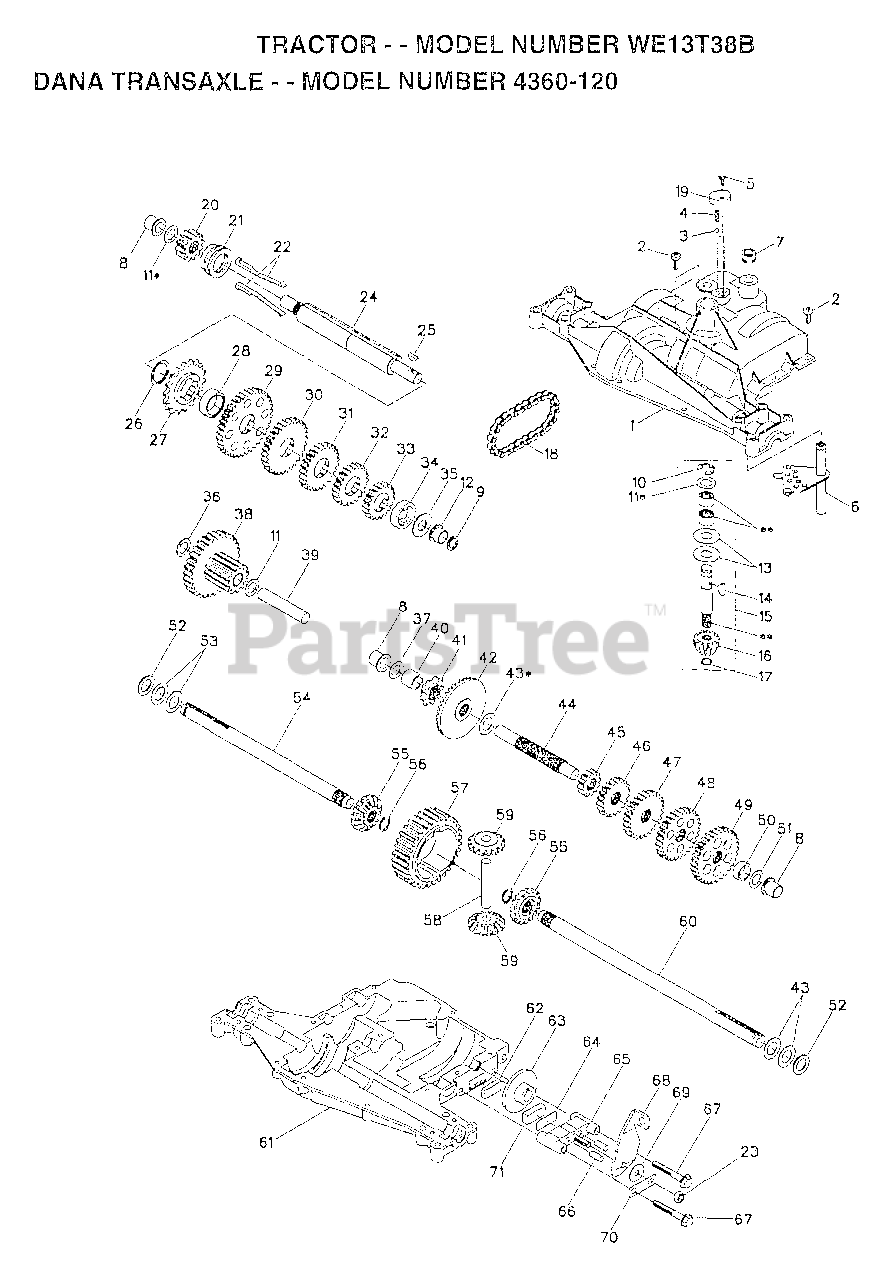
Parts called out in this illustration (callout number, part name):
1	HOUSING.UPPER.DANA.(5305J)
4	"SPRING, DETENT LT"
5	SCREW.TAPPING.1/4-20X.734
6	KIT SHIFTER ASM
9	SEAL.OIL.DAN.5508
10	RETAINING RING LT
11	ASM KIT SHIM 4689
12	BEARING.FLNG.5511
13	WASHER T
14	KEY WOODRUFF-DANA
15	INPUT SHAFT KIT 6250
16	PINION.BEVEL.12T(5620)
17	"RING,RETAINING LT"
18	"CHAIN,24 PTCH LT"
19	COVER.DETENT.(5584)
20	GEAR.SPUR.12T.(5627)
21	CLUTCH.COL.5467
22	ASM KIT CLTCH KEY
23	NUT.LOCK.5/16-24
24	SHAFT INTERM DANA
25	WOODRUFF KEY
26	"RING,RETAINING LT"
27	SPROCKET 18T T
28	SPACER YT
29	GEAR SPUR 37 TTH
30	GEAR SPUR 30T
31	GEAR 25T LT
32	GEAR SPUR 22 TT
33	SPUR GEAR 19T
34	SPACER
35	"WASHER, PLAIN LT"
36	WASHER 045
37	WASHER 031
38	ASSY.GEAR.6153 12T&30T
39	SHAFT IDLER
40	SPACER T
41	SPROCKET 9T LT
42	GEAR.BEVEL.36T(5621)
43	ASM KIT SHIM
44	SHAFT T
45	GEAR SPUR 12 TTH
46	GEAR SPUR 20T
47	"GEAR, SPUR 25T LT"
48	GEAR 28T T
49	"GEAR, SPUR 31T LT"
51	WASHER 060
52	NEOPRENE WASHER
53	WASHER 031
54	AXLE.LH(5528-1)
55	MITER 5270 12T.SPLINED
56	RING.RETAINING.(5270)
58	SHAFT T
59	MITER 5623.12T.IDLER
60	AXLE.RH.(5528-2) DANA
61	HOUSING LOWER TNS
62	PUCK T
63	BRAKE DISC. T
64	SPACER LT
66	PIN T
67	SCREW.(5562) .5/16-18X2.35
69	WASHER LT
70	BRACKET, ANTI-ROTATION
71	PUCK T
